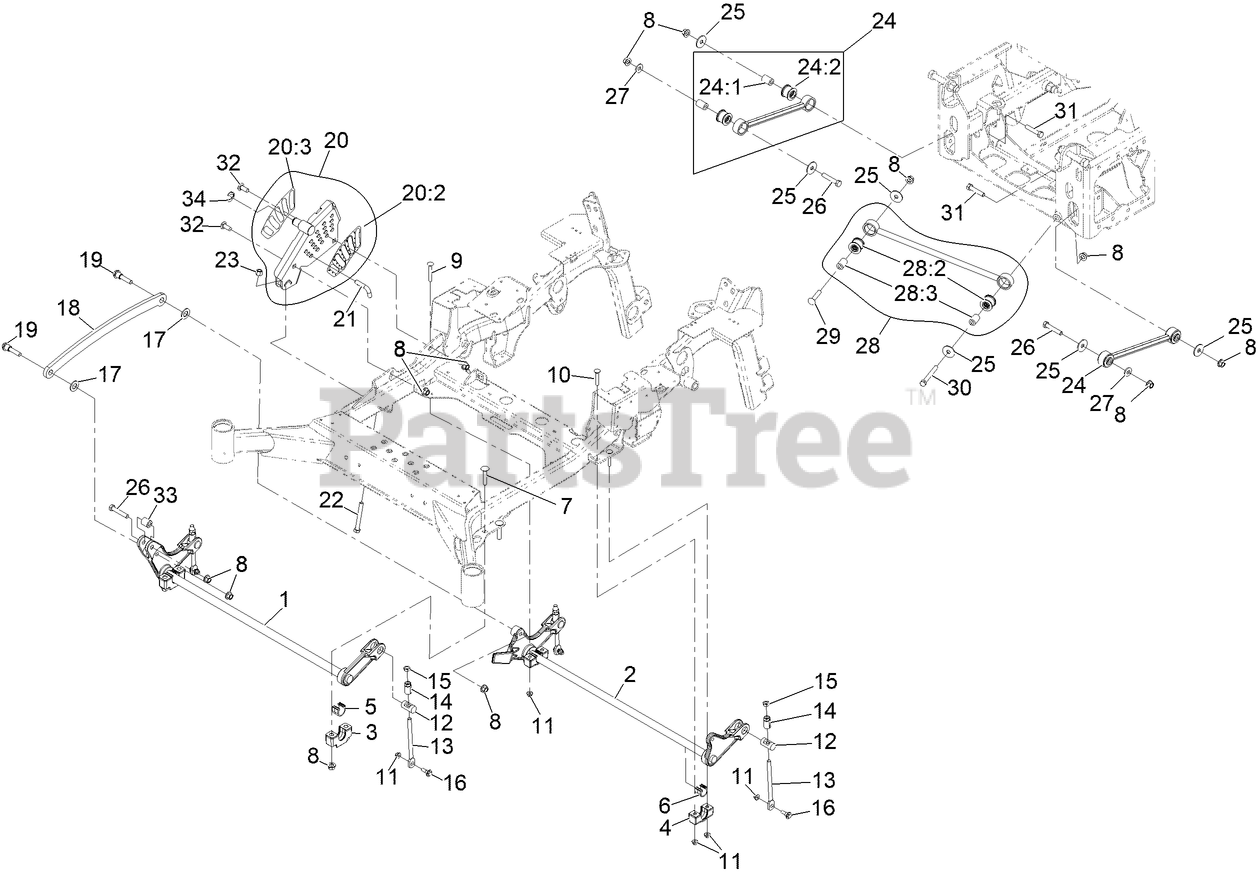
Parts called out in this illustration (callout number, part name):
1	DECKLIFT-FRONT
2	LIFT-DECK, REAR
3	SUPPORT-CROSS SHAFT, BEARING
4	SUPPORT-CROSS SHAFT, BEARING REAR
5	BEARING-CROSS SHAFT, FRONT
6	BEARING-CROSS SHAFT, REAR
7	BOLT-CARR
8	NUT-LOCK
9	SCREW-CARR
10	SCREW-CARR
11	NUT-HF, NI
12	TRUNNION
13	LINK-ADJUSTER, DECK LIFT
14	ADJUSTER-LIFT, DECK
15	NUT-JAM
16	SCREW-SHOULDER, HHF
17	WASHER-FLAT
18	LINK-LIFT, DECK
19	SCREW-HHF, SHOULDER
20	HOC ASM
20:2	DECAL-HEIGHT OF CUT
20:3	DECAL-HEIGHT OF CUT, OUTER
21	PIN-HOC
22	BOLT-TAP
23	NUT-LOCK, NI
24	DECK STRUT ASM 85A
24:1	SPACER
24:2	BUSHING-RUBBER
25	WASHER-THRUST
26	SCREW-HH
27	WASHER-SPRING
28	PANHARD ROD ASM
28:2	BUSHING-SUSPENSION, RUBBER
28:3	SPACER
29	SCREW-CARR
30	SCREW-HH
31	SCREW-HH
32	SCREW-CARR, SHORT NECK
33	SPACER-PIVOT
34	RING-RETAINING
